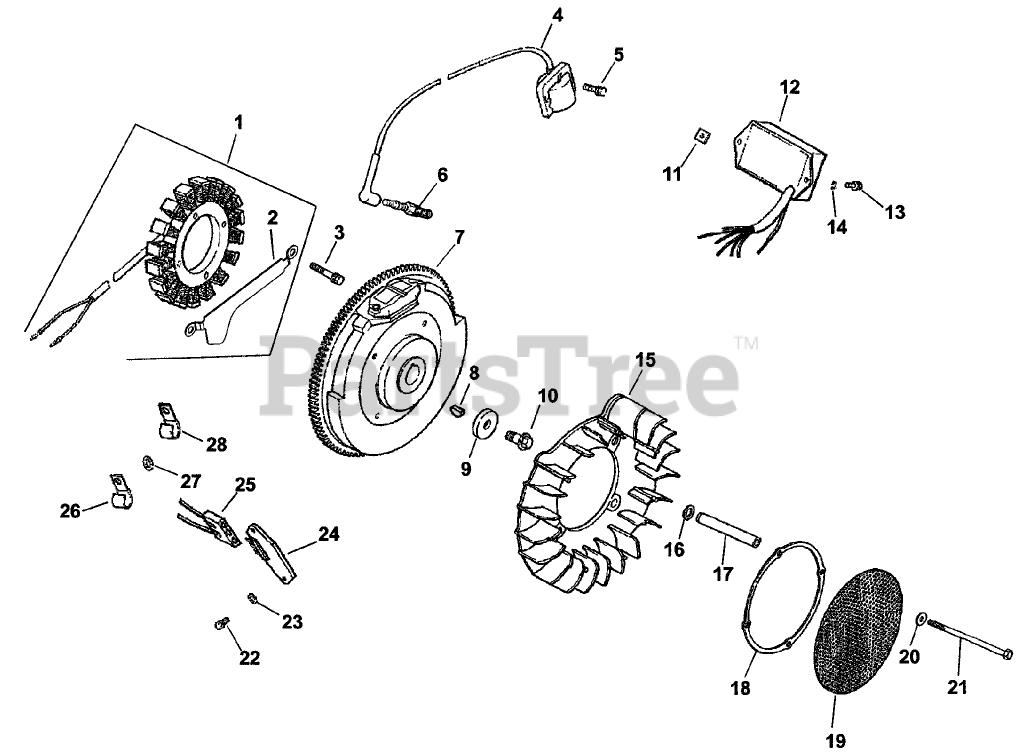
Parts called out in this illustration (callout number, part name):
1	Kit-Stator, 15 amp (Incl. Ref. # 2)
2	Bracket-Wire, Stator
3	SCREW-THREAD FORMING (M5X0.8X25)
4	Module-Ignition
5	Screw-Socket, Hex (M5x0.8x25)
6	Spark Plug
7	Flywheel
8	KEY (3/16 X 5/8)
9	WASHER-FLAT (13/32)
10	SCREW-FLANGE (M10X1.5X45)
11	NUT-PLASTIC
12	Module-Advance, Speed
13	SCREW-PPH (11-16X1/2)
14	Washer-Lock, Internal Tooth (1/4)
15	Fan
16	Washer-Spring (10MM)
18	Ring-Support
19	Screen-Grass
20	WASHER-FLAT (1/4)
21	Screw-Socket Truss Head, Cap
22	SCREW-PHL HD (11-16X.88)
23	WASHER-FLAT (.188)
24	Rectifier-Regulator, 15 amp
25	Connector (3 contact)
26	CLIP-CABLE
27	WASHER-FLAT (1/4)
28	Clip-Cable
